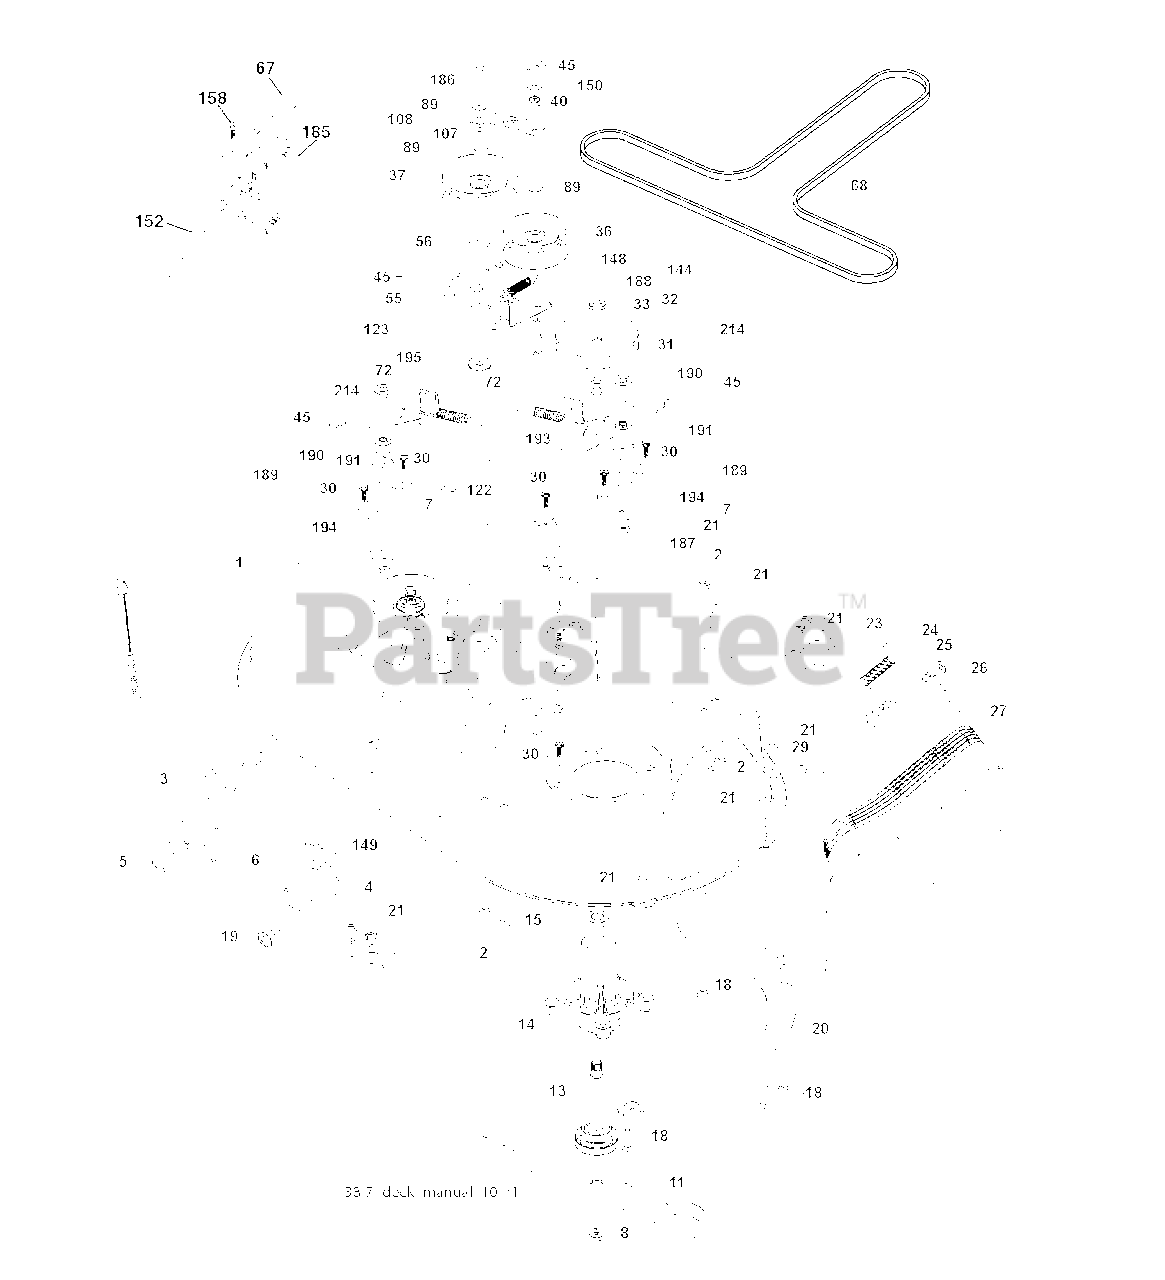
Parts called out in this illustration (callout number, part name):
1	DECK.WELDMENT.38"2005
2	BOLT
3	BRKT ASM SWAY BAR
4	BRACKET DECK SWAY BAR 38"/42"
5	RETAINER-SPRNG RB
6	BAR SWAY DECK
7	NUT.71038.31-18.HEX.NYLOCK
8	BOLT.WASHER.ASM.7/16-2
11	BLADE 38" PREMIUM
13	SHAFT.ASM.MDRL.N/GREASE.38
14	HOUSING MANDREL
18	BOLT
19	BOLT SHD 5/16-18
20	BAFFLE VORTEX
21	LOCKNUT
23	BRKT.DEFLECTOR.38"2005+
24	CAP-SLEEVE LT
25	SPRING.TORSION.DEFLECT
26	NUT PUSH M
29	ROD.HINGE
30	SCREW, WASHER HEAD
31	WASHER.SPACER.MANDREL
32	PULLEY MANDREL
33	NUT.FLANGE.LOCK.TOP
36	FLAT IDLER PULLEY
37	PULLEY.IDLER.FLAT.UNPLATED
40	LOCKNUT
45	RETAINER M
55	IDLER ARM
56	SPACER.RETAINER.MOWER
67	KNOB T (1/2-HOLE)
68	V-BELT.MOWER.38"2005+
72	SPRING.BRAKE.RETURN.38"
89	WASHER
107	SPACER.IDLER.ARM
108	STIFFENER.IDLER.ARM
122	ROD, BRAKE LH LINK
123	LINK.BRAKE.38"RIGHT
144	KEEPER BELT
148	IDLER RETURN SPRING
149	SPRING.RETAINER.YELLOW.ZINC
150	WASHER LT
152	CABLE.CLUTCH.38".SERVICE
158	SCREW
185	HEAD ASM. CABLE CLUTCH
186	SCREW.HXWSH.3/8
187	KEEPER BELT
188	BOLT, CARRIAGE IDLER
189	STAND, BRAKE
190	ARM, BRAKE
191	SPACER, BRAKE
193	KEEPER BELT RH MANDREL
194	GUARD BRAKE
195	WASHER 12/32X2X10GA
214	BOLT/WASHER ASM 5/16-18
